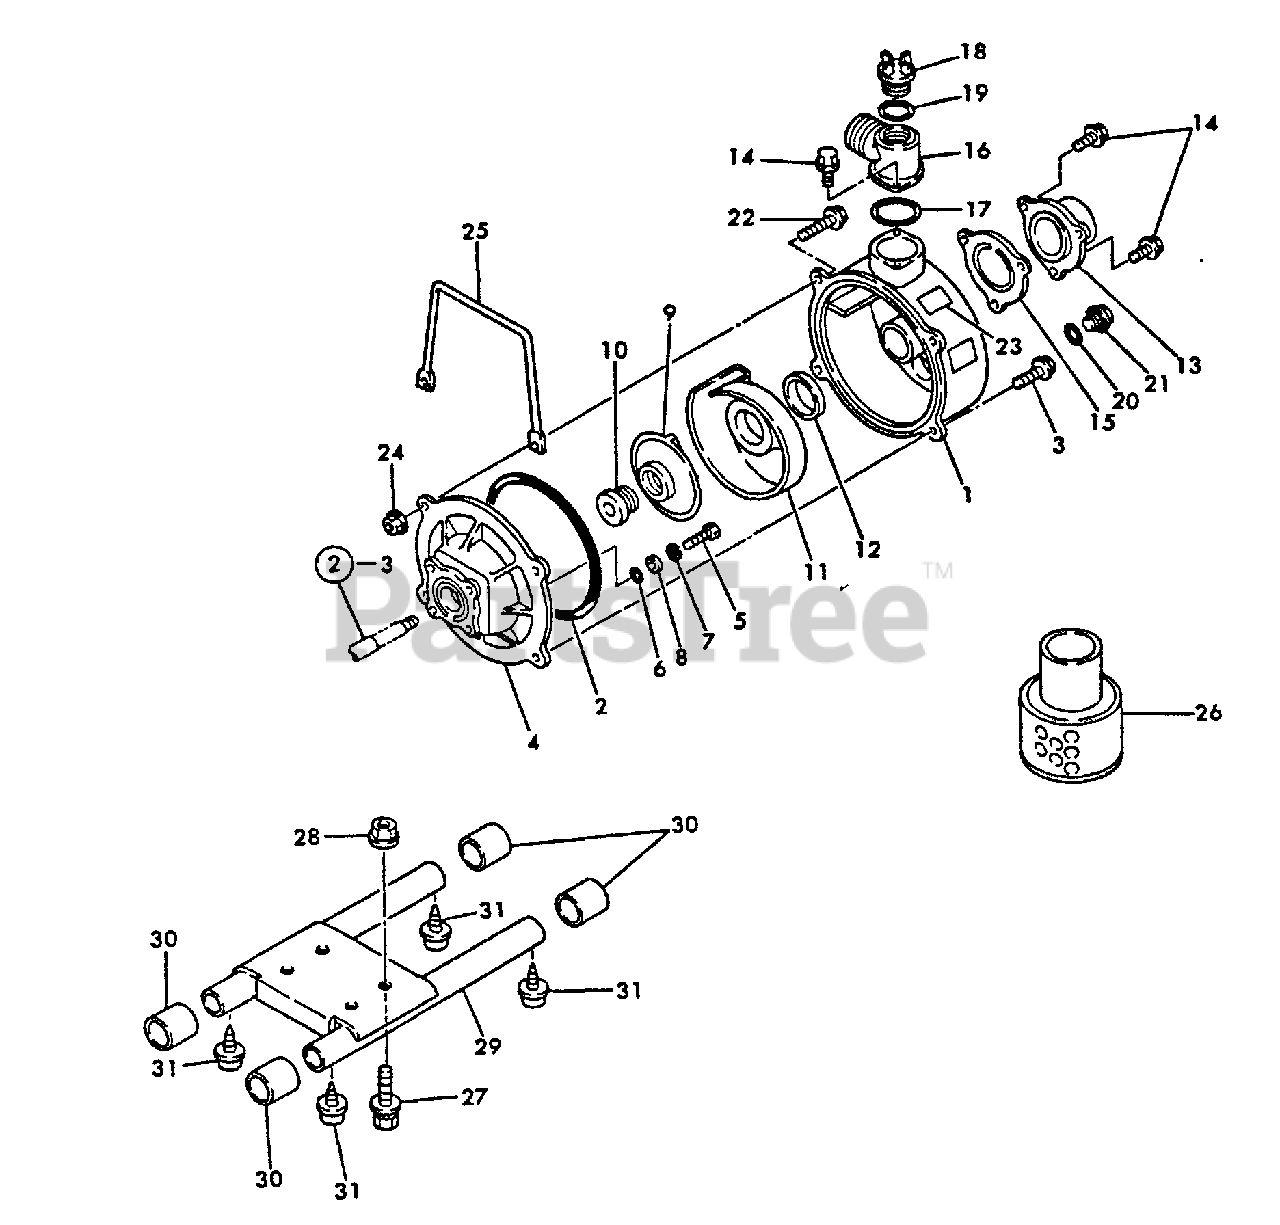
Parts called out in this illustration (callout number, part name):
1	CASING
2	GASKET, CASING
3	BOLT - 8X25
4	COVER, PUMP CASE
5	BOLT - 8X48
6	GASKET
7	LOCKWASHER
8	WASHER - 8
9	IMPELLER, SHIM 0.3 Y40106000000
10	SEAL
11	CASING, INNER
12	GASKET, INNER CASING
13	CASE
14	BOLT - 6X20
15	VALVE, CHECK
17	GASKET, BEND
19	GASKET, PLUG
20	GASKET, DRAIN BOLT
21	BOLT, DRAIN - 12X20
22	BOLT - 8X40
23	LABEL - CAUTION
24	NUT - 8
25	HANDLE
26	STRAINER, DEBRIS
27	BOLT - 8X20
28	CASE, PUMP
29	BASE
31	SCREW
